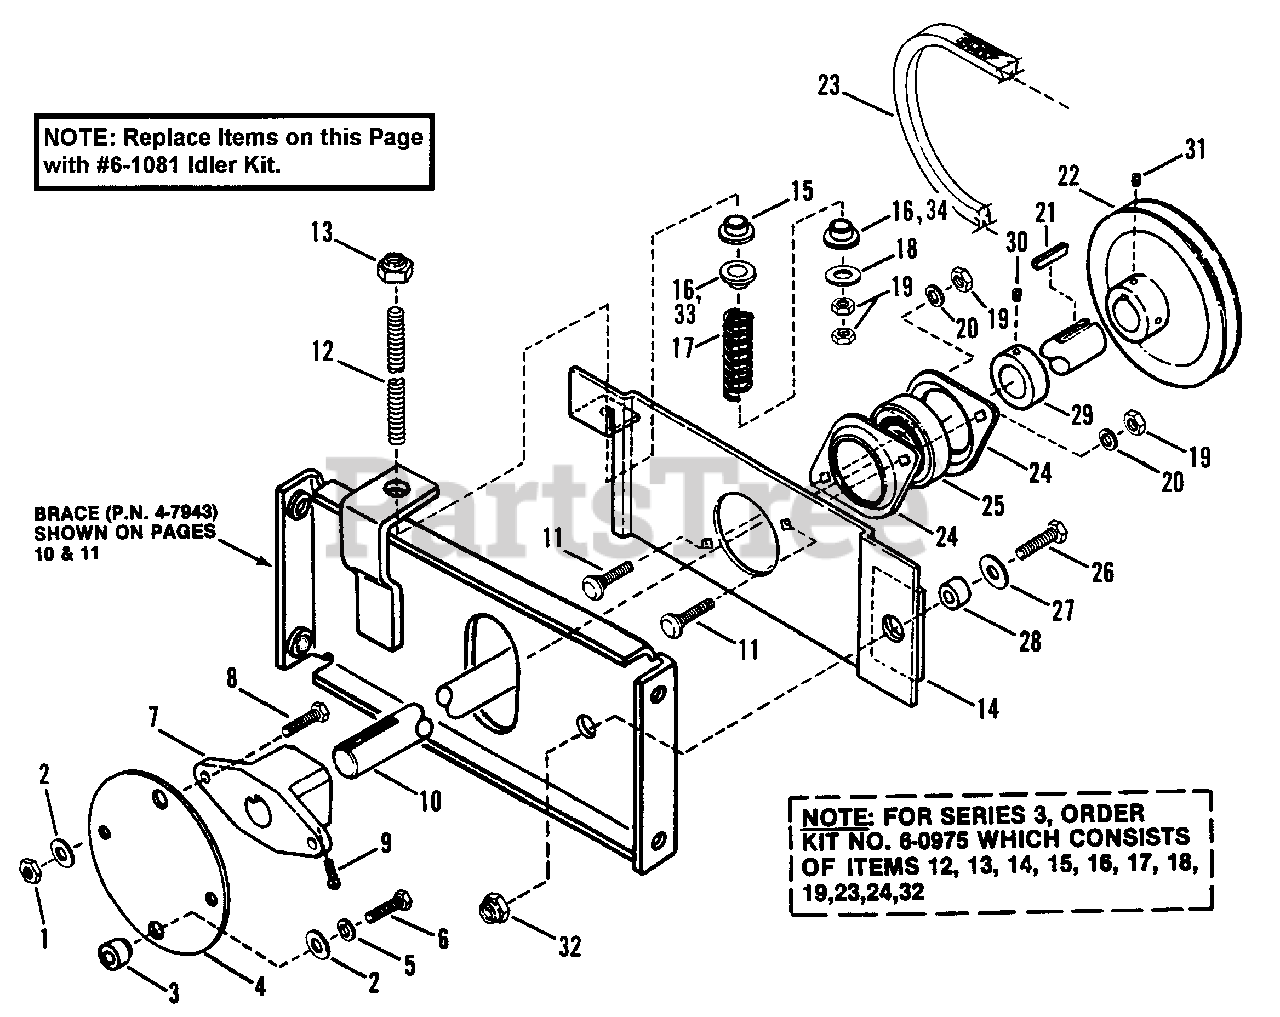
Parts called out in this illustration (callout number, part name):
1	NUT, 3/8-16 Hex Center Lock, Grade B or 5
2	WASHER, 13/32" Flat
3	SPACER, Flex Coupling
4	DISC, Flex Coupling
5	WASHER, 3/8 Split Lock
6	SCREW, 3/8-16 x 1-1/4" H.H.C.
7	HUB, Flex Coupling
8	SCREW, 3/8-16 x 1" Hex Head Cap
9	SCREW, 5/16-18 x 1/2" Square Head, Cup Point Set
10	SHAFT, Drive
11	BOLT, 5/16-18 x 3/4" Carriage
12	ROD, 5/16-18 x 8" Threaded
13	NUT, 5/16-18 Hex Nyloc
14	MOUNT, Bearing
15	BUSHING, Nylon
16	WASHER, Flange
17	SPRING, Belt Tension
18	WASHER, 5/16" Flat
19	NUT, 5/16-18 Hex, Gr. B or 5
20	WASHER, 5/16 Split Lock
21	KEY, Pulley, 3/16 x 3/16 x 1"
22	PULLEY, Drive, 4-1/4" O.D.
23	BELT, Traction Drive
24	FLANGETTE
25	BEARING
26	SCREW, 5/16-24 x 1" Hex Head Cap
27	WASHER, 5/16" x 1-1/4" x 3/32" Flat
28	SPACER, 5/8" O.D.
29	COLLAR, Lock
30	SCREW, 1/4-20 x 1/4" Socket Hd.
31	SCREW, 5/16-18 x 5/16" Socket Head
32	NUT, 5/16-24 Hex Nyloc
33	SPRING BUSHING, Upper
34	SPRING BUSHING, Lower
47943	Brace
60975	Kit, Series 3
61081	Idler Kit
